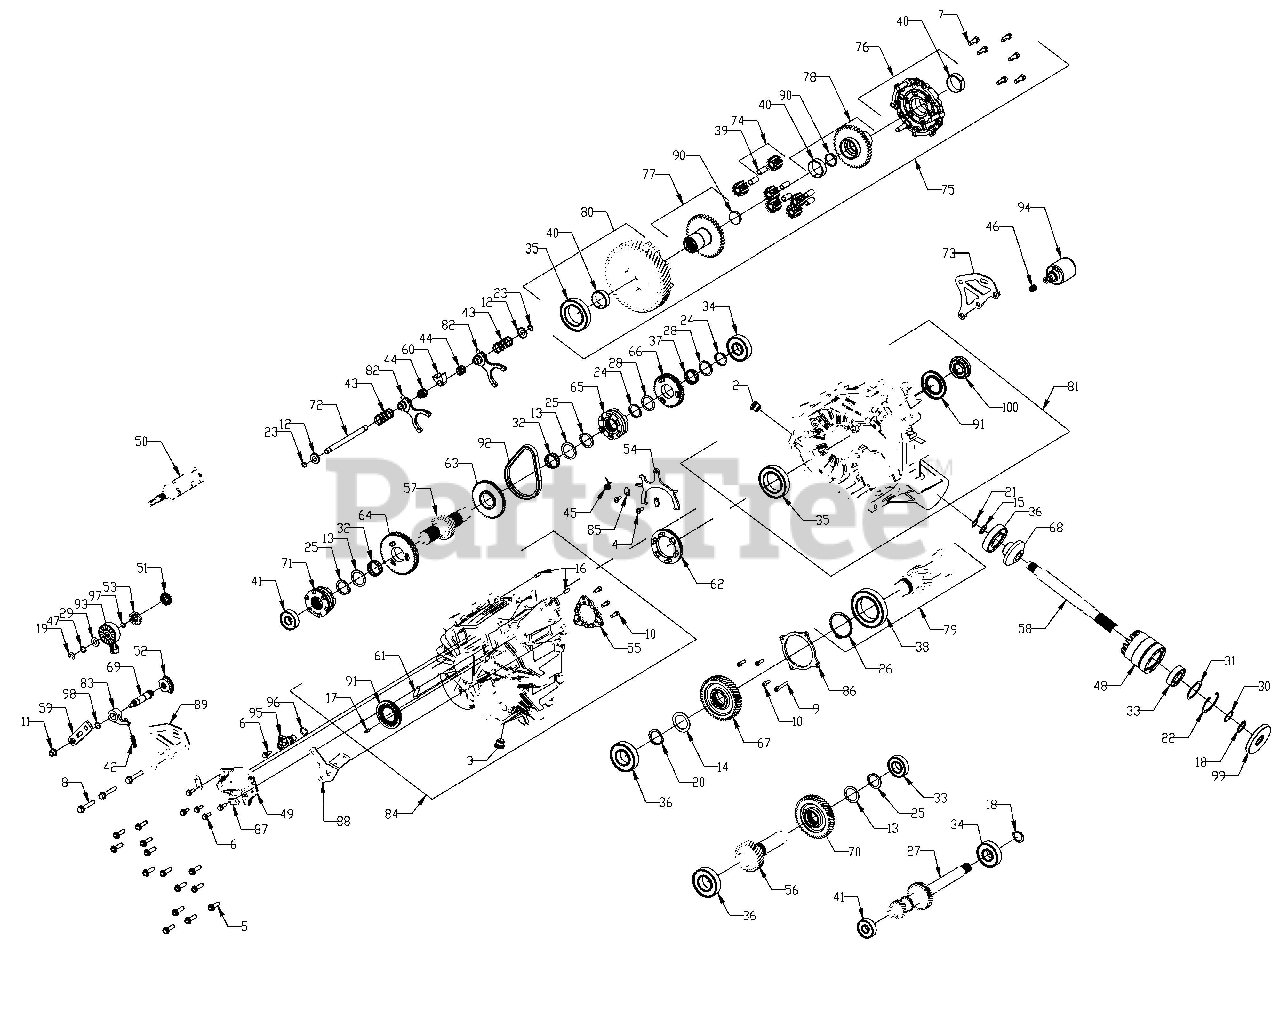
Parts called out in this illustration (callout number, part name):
2	PLUG-SKT HD 1SO 6149,M18 X 1.5
3	PLUG-SOCKET HEAD W/MAG,M18X1.5
4	SCREW, TORX PAN HD M6 X 1 X 16
5	SCREW-HEXFLANGEHEAD,M8X1.25X30
7	SCREW-CAP HH,M8 X 1.25 X 20
9	SCR-M6X1.0X40,SOC/CAP(105344)
10	SCR-SCKT HD,CP,M6X1X18(105355)
11	NUT-M8X1.25,HXFLG,NYLN(110093)
12	WASHER-CUP
16	PIN, DOWEL, 6 X 20
17	SPRING-SLOTTED PIN,6MM
18	RING, SNAP
19	RING-RETAINING
20	RING,RETAINING
21	RING,RETAINING,EXTERNAL SHR-66
22	RING,RETAININGBASICINTRNL2.047
23	RING-RETAINING
24	RING,RETAINING
25	RING, RETAINING, EXTERNAL
26	RING, RETAINING
27	SHAFT-PINNION,INPUT,BOSS,LW
28	WASHER,THRUST
29	WASHER,THRUST,.446X.88X.025
30	SHIM 1.180 X .995
31	SHIM 2.040 OD X 1.630 ID
32	BEARING,NEEDLE
35	BEARING, BALL
36	BEARING-BALL
37	BEARING,NEEDLE
38	BEARING, BALL
39	BEARING,PLAIN,10X12X25
40	PLAIN,BEARING 40X44X15
41	BEARING, BALL
42	SPRING-COMPRESSION
43	SPRING-COMPRESSION
44	SPRING-COMPRESSION
45	SPRING, TORSION RETURN
46	SPRING,COMPRSSN.54ODX.44IDX.05
47	WASHER-SPRING,210393
48	TUBE, SNORKLE MACH
49	COVER,GEARCASE
50	DRUM-SHIFT,MACH.(255289)
51	GEAR-SECTOR,16T
52	GEAR-SECTOR,31T-CUT TO 11T
53	DETENT STAR
54	SHIFT FORK (270507)
55	PARK PLATE (270509)
56	SHAFT, IDLER, 29T
57	SHAFT,REVERSE,25T (285878)
58	SHAFT-FRONT OUTPUT(285914)
59	BELLCRANK
60	COLLAR-SHIFT
61	TUBE-VENT,90-1/4" HOSE
62	DOG-ENGAGEMENT
63	SPROCKET-48T,6-FACE(352854)
64	GEAR-LOW,67T(352856)
65	DOG, ENGAGEMENT, 6-FACE
66	GEAR, 53T
67	GEAR, 46T, STAGE 3
68	GEAR-13T,FRONT OUTPUT(352957)
69	SHAFT, SHIFT
70	GEAR,48T STAGE 2 (353115)
71	SHIFT DOG, PARK/LOW (353357)
72	RAIL-SHIFT SHAFT(353622)
73	WELD-REAR MOUNT BRKT
74	GEAR SUBASSEMBLY
75	DIFF-LOCKING (411600)
76	SUBASSY-COVER,DIFF (411601)
77	SUBASSY-GEAR,39T SIDE (411607)
78	SUBASSY-GEAR,39T SIDE (411608)
79	ASM-SUB,PINION SHAFT(411759)
80	SUBASSY-GEAR,53T (411797)
81	SUBASSY,LH CASE(411919)
82	SHIFT FORK SUBASSEMBLY
83	ROLLER PAWL
84	SUBASSEMBLY,RH CASE (411982)
85	RETAINER-FORK
86	COVER, BEARING, CENTER DRIVE
87	BRKT-MOUNT(430592)
88	BRKT-MNT,HARNESS
89	BRKT-REAR MOUNT
90	PLUG,EXPANSION,1 1/4
91	SEAL-TRIPLE LIP,VITON,40X70X7
92	CHAIN, SILENT
93	PIN-GEAR POSITION SWITCH
94	SOLENOID
95	SENSOR-SPEED,TRANS
96	O-RING, -113
99	SEAL-TRIPLE LIP 25X80X10
